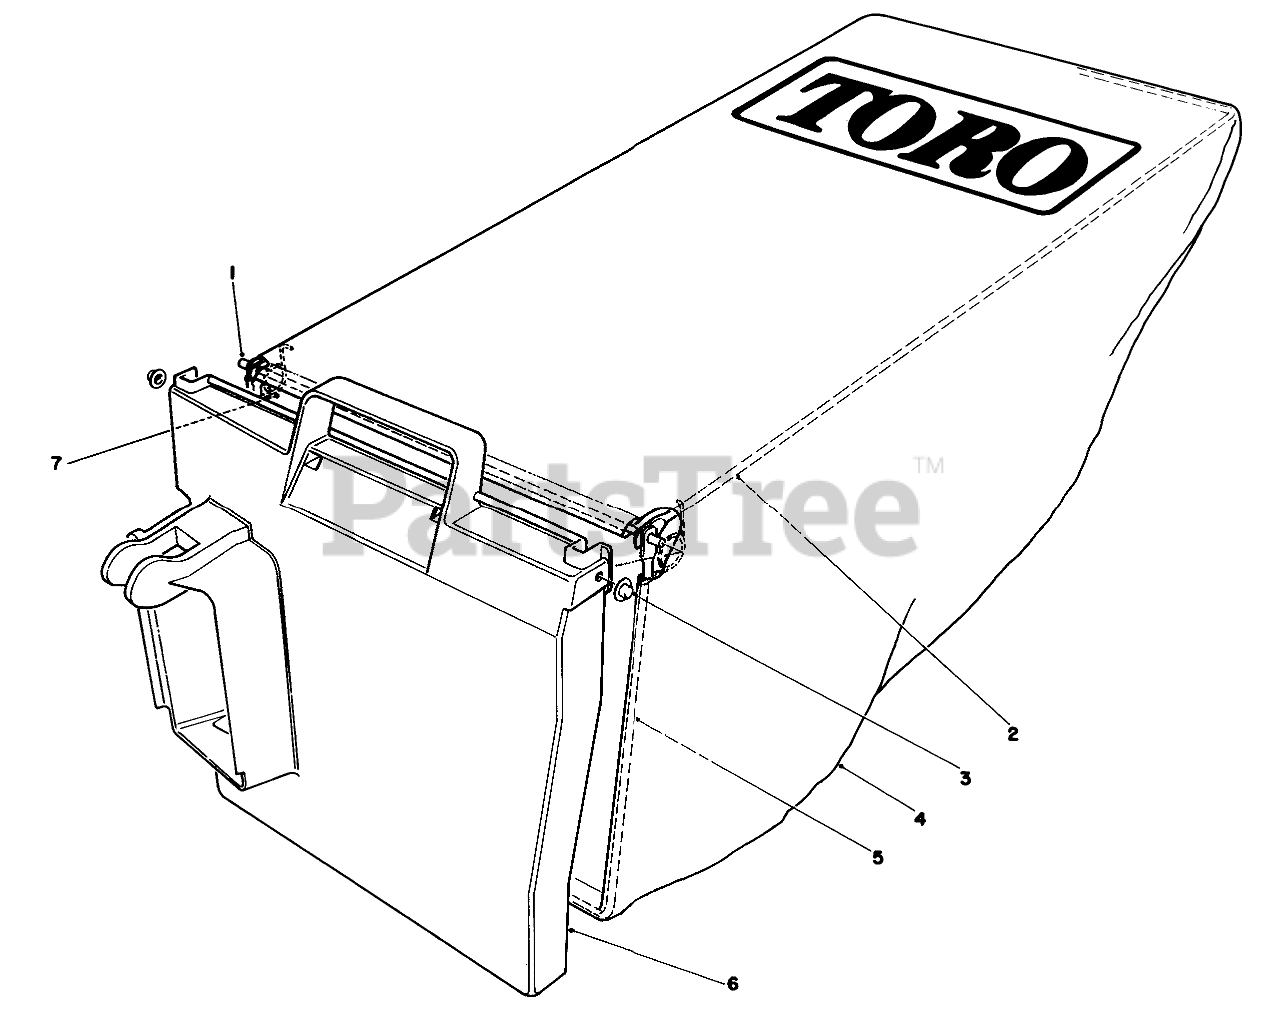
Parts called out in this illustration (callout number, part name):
1	HINGE PIN
2	BAG FRAME
3	NUT-PUSH
5	BAG FRAME
6	GRASS BAG DOOR
7	SPRING
